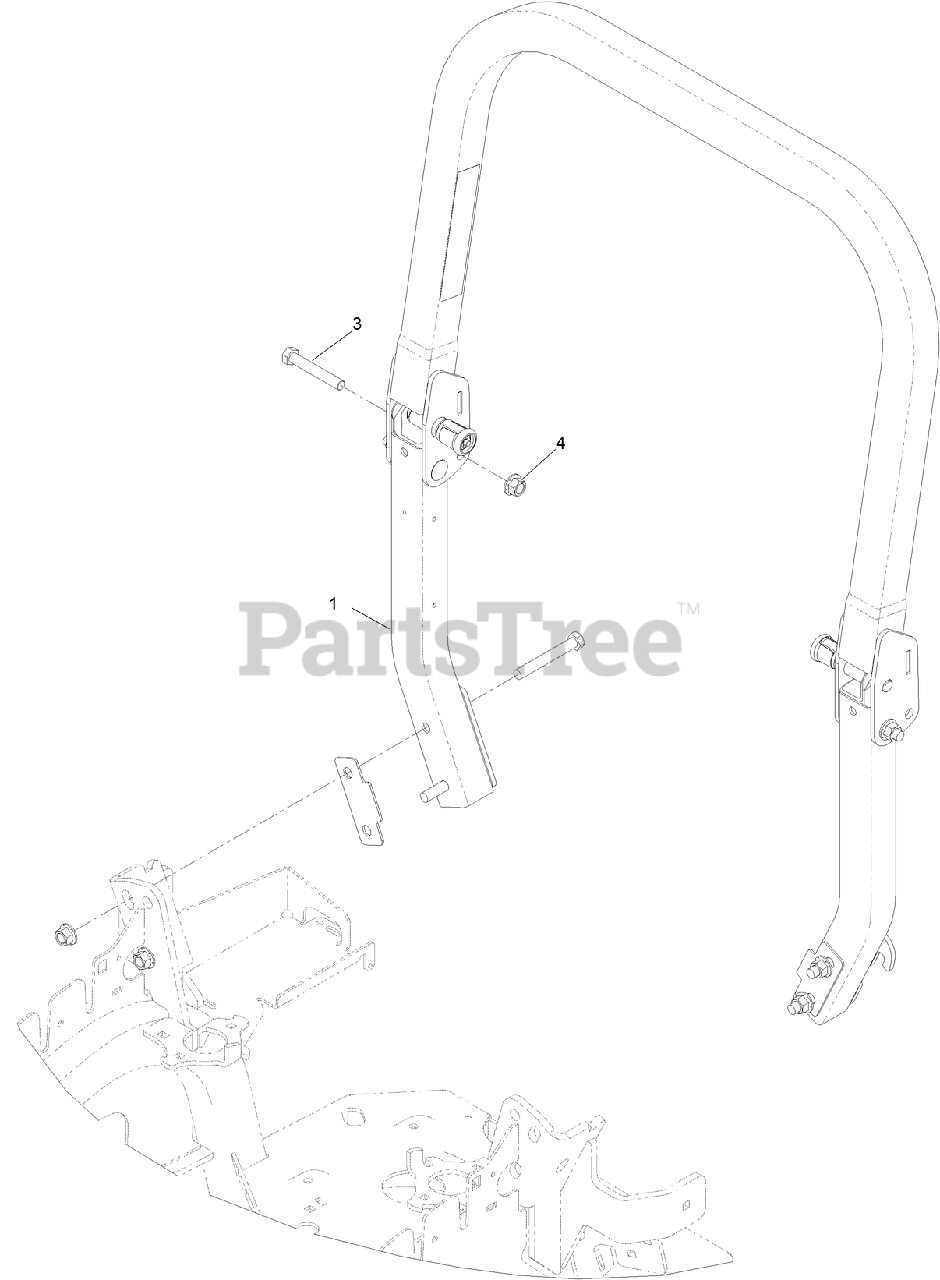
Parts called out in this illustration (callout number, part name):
1	ROPS ASM
3	SCREW-HH
4	NUT-LOCK
